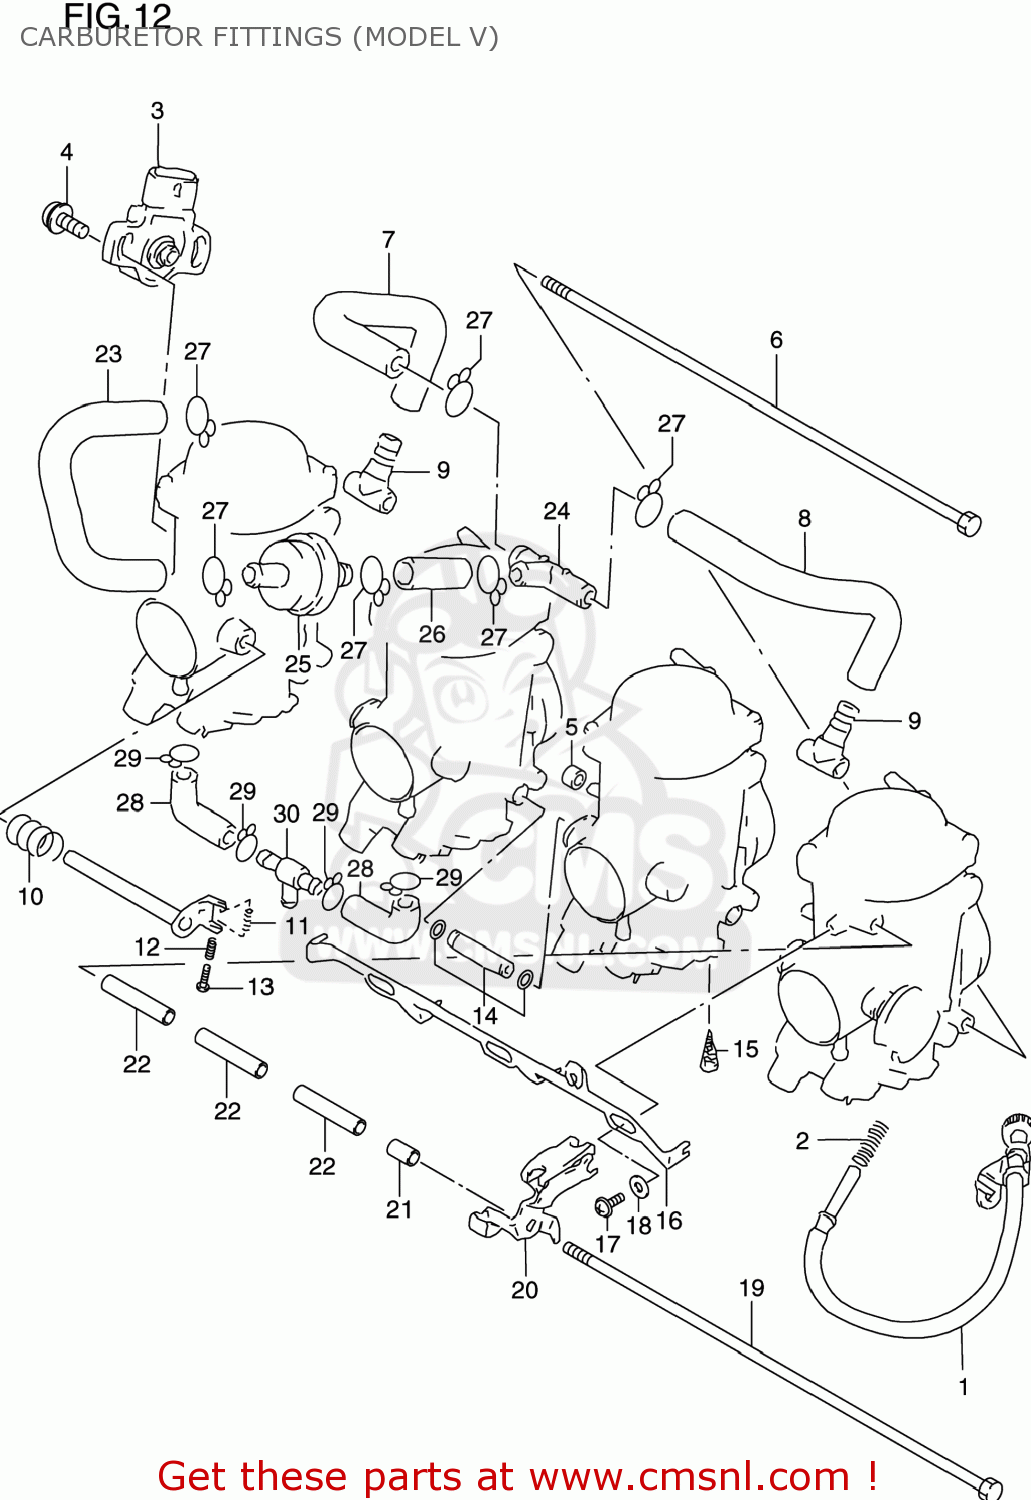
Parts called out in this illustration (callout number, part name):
1	ADJUSTER
2	SPRING
3	SENSOR ASSY,THROTTLE
4	SCREW, SENSOR
5	PIPE
6	BOLT
7	HOSE
8	HOSE
9	3 WAY
10	SPRING
11	SPRING,THROTTLE SCREW
12	SPRING
13	SCREW
14	NIPPLE,CARBURETOR
15	FILTER
16	LEVER,STARTER
17	SCREW
18	PACKING
19	BOLT
20	BRACKET
21	PIPE
22	PIPE
23	HOSE,AIR VENT(NO.1)
24	JOINT
25	FILTER,AIR VENT
26	HOSE(11X15X600)
27	CLIP
28	HOSE
29	CLIP
30	NIPPLE
